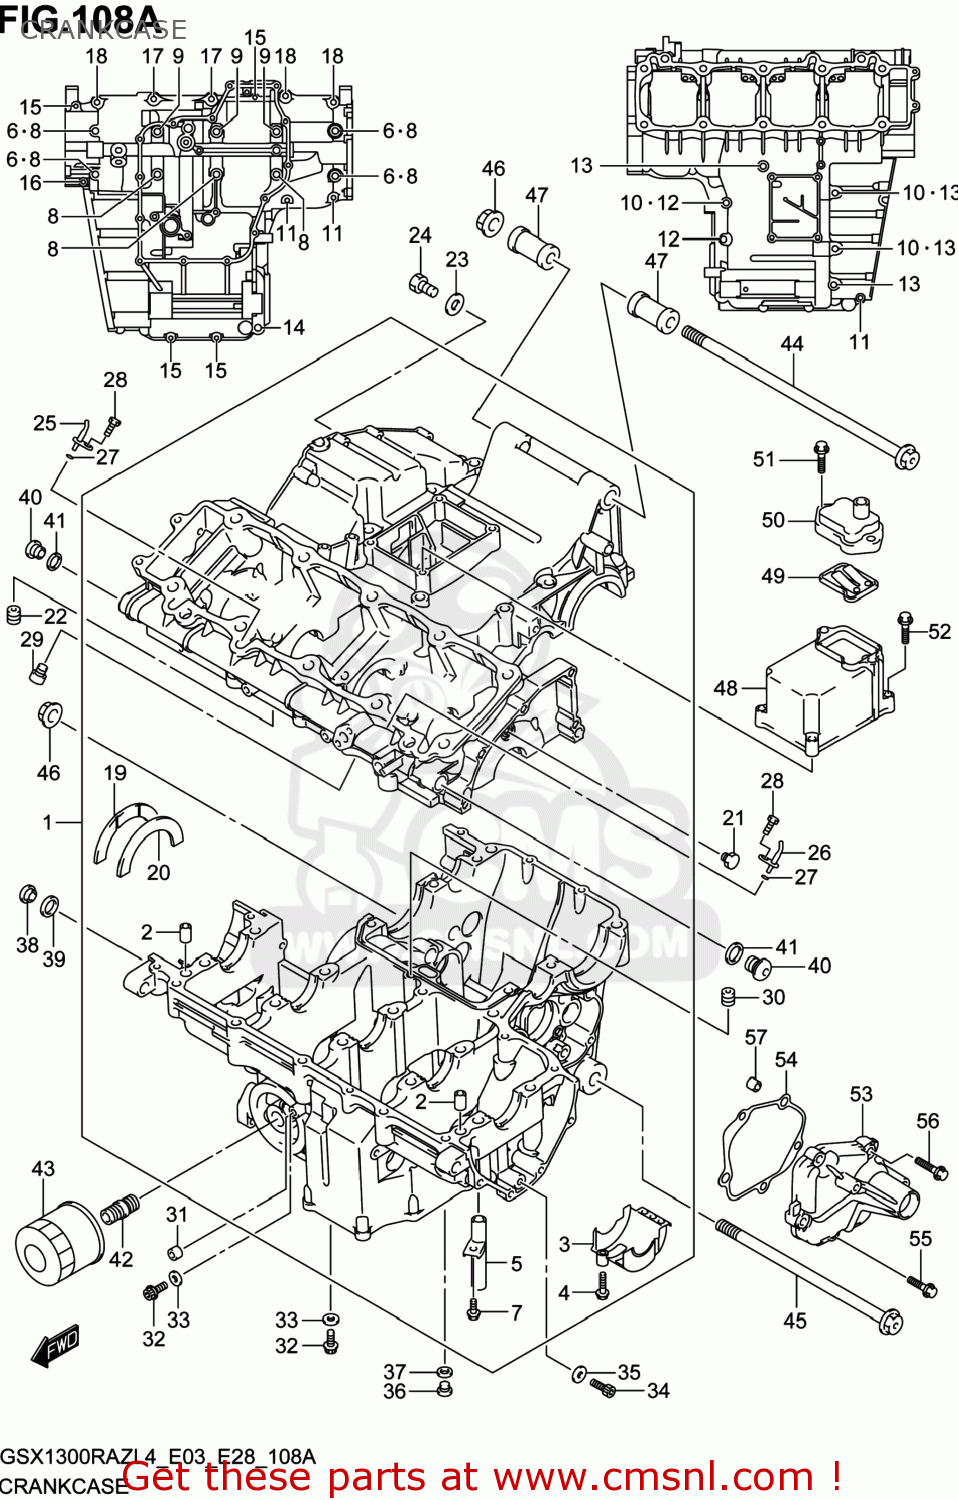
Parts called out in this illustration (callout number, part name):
1	CRANKCASE SET
2	PIN,CRANKCASE
3	SEPARATOR,OIL
4	BOLT
5	UNION,BREATHER
6	GASKET(10.2X20X2).3 (NAS)
7	BOLT
8	BOLT(9X95)
9	BOLT(9X115)
10	GASKET(8.2X14X1) (NAS)
11	BOLT
12	BOLT
13	BOLT
14	BOLT
15	BOLT
16	BOLT
17	BOLT(8X60)
18	BOLT(8X50)
19	BEARING,CRANK THRUST,L
20	BEARING,CRANK THRUST,L
21	JET,MAGNETO COOLING
22	JET,AIR(100)
23	GASKET(5.8X13X1.2) (NAS)
24	BOLT
25	JET,PISTON COOLINGR
26	JET,PISTON COOLING
27	O RING(D:1.2,ID:4)
28	BOLT(6X12)
29	BOLT(6X10)
30	JET,AIR(180)
31	JET,OIL PAN GALLERY
32	BOLT
33	GASKET(5.8X13X1.2) (NAS)
34	BOLT
35	GASKET(8.2X14X1) (NAS)
36	PLUG(10X10)
37	GASKET(10X14X3.6) (NAS)
38	PLUG,16X8
39	GASKET(16X22X2) (NAS)
40	PLUG,14X12
41	GASKET(13.8X18.8X4.8) (NAS)
42	UNION,OIL STAND
43	FILTER ASSY,ENGINE OIL
44	BOLT(12X320)
45	BOLT(12X243)
46	NUT
47	SPACER,ENG MTG(L47)
48	COVER,BREATHER
49	VALVE ASSY,BREATHER REED
50	COVER,BREATHER REED VALVE
51	BOLT
52	BOLT
53	COVER,GEAR SHIFT
54	GASKET,GEAR SHIFT COVER (NAS)
55	BOLT
56	BOLT
57	PIN
